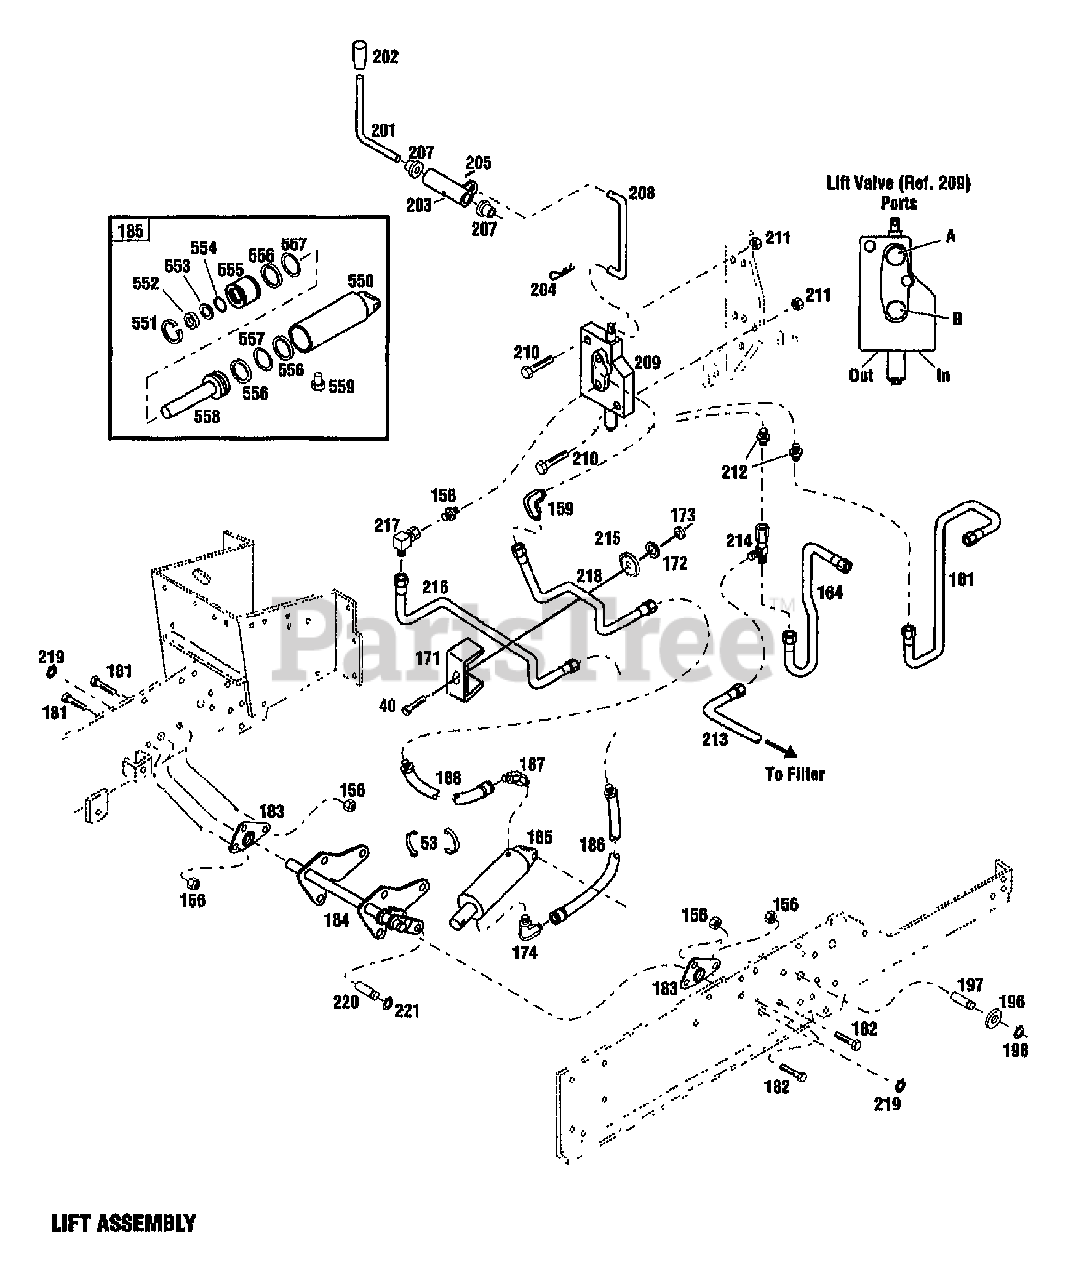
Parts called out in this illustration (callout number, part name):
40	SCR-HH 5/16-18X1.0 G5 ZP
53	LINER-CHUTE
156	NUT-HFLK 5/16-18 ZP
158	CONNECTOR
159	ELBOW
161	TUBE-HYD PB VALVE
164	TUBE-HYD S C U TANK
171	CLAMP
172	WASHER-LK .312 ZP
173	NUT-HEX 5/16-18 ZP
174	ELBOW
181	SCR-LOCK
182	SCR-LOCK
183	BEARING-LIFT SHAFT
185	ASSM-CYL HYDRAULIC
186	ASSM-HOSE
187	ELBOW
188	ASSM-HOSE
196	WASHER-1.5X.755X.062
198	RING-RETAIN EXT .707 ID
201	LEVER-CONTROL
202	KNOB-SHIFT LEVER
203	ARM-CONTROL
204	PIN-CLIP .08
205	PIN-DRIVE
207	BRG-FLANGE
208	LINK-VALVE
209	VALVE-HYDRAULIC
210	SCR-HFLK 1/4-20X2.00 G5ZP
211	NUT-HF/LK 1/4-20 ZP
212	CONNECTOR
213	TUBE-HYD RETURN
214	TEE-SWIVEL
215	WASHER-FLAT 1.25X.406X.179
216	TUBE-HYD VALVE TO ROD
217	ELBOW
218	TUBE-HYD VALVE TO HEAD
219	RING-RETAINING
221	RING-RETAIN .625 ID
550	ASSM-CYL HYDRAULIC
551	RING-RETAIN INT 2.210 DIA
552	SEAL-OIL
553	RING-BACK/UP
554	RING-O .984 ID
555	HEAD-CYLINDER
556	RING-BACK/UP
557	RING-O 1.6 ID
558	ASSM-ROD HYDR CYLINDER
559	PLUG-PIPE
